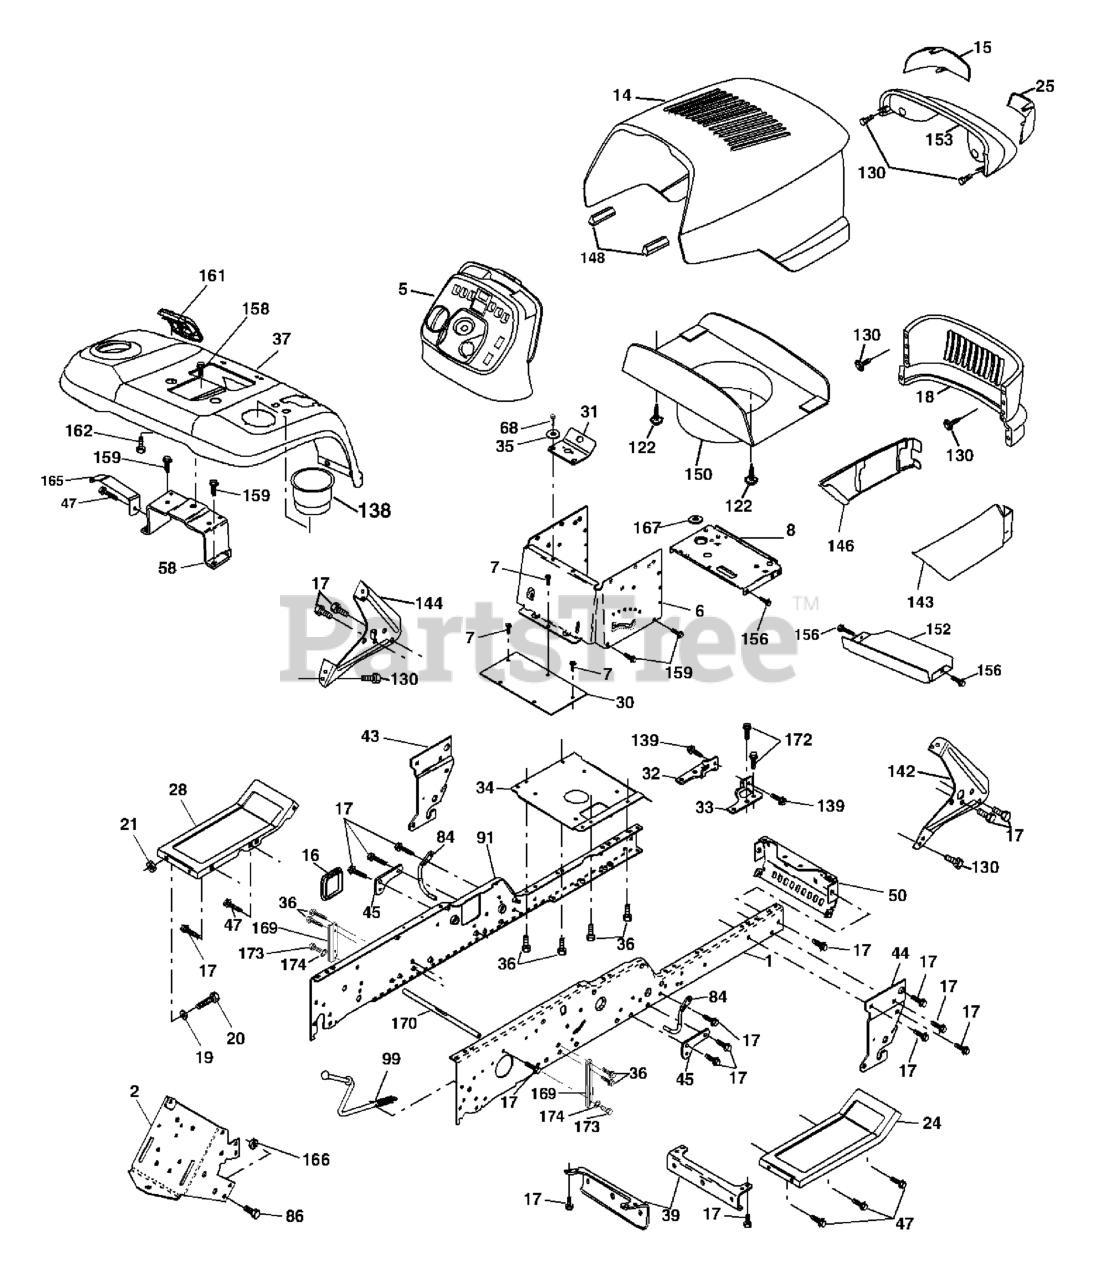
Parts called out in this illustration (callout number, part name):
1	KIT.RAIL.CHASS.RH.GT
2	DRAWBAR, GT
5	DASH
6	DASH VGT, LOWER
7	SCREW
8	SUPPORT, BATTERY
14	HOOD
15	LENS LH
16	COVER ACCESS
17	SCREW, 3/8-16X3/4
18	GRILLE.STEALTH P/L.YTGT.GREY
19	WASHER
20	BOLT
21	NUT
24	FOOTREST PNT RH
25	LENS RH
28	FOOTREST PNT LH
30	SADDLE.HYDRO.95
31	BRACKET SUPT 1-PC VGT STEERING
34	PLATE ASM ENG CHASSIS
35	WASHER
36	SCREW 5/16"
37	KIT.FENDER.YTGT.W/S
39	BRACKET AXLE, FRONT
43	FRONT SUSPENSION BRKT LH
44	FRONT SUSPENSION BRKT RH
45	BRACKET ARM SUSPENSION
47	SCREW LT
50	BRACKET, CHASSIS FRONT
56	BRACKET ASM., SUSP CHASSIS LH
58	BRACKET ASM., FENDER
68	Screw, 5/16-18 x 1/2
84	UPSTOP 54"
86	BOLT FIN HEX 7/16-14 X 1
91	KIT.RAIL.CHASS.LH.GT
99	ROD ASM, BYPASS
122	SCREW.WSHD.HEX10-32X5/8
130	SCREW
138	CUPHOLDER.YTGT.TWIST L
139	BOLT, SHOULDER 5/16-18
142	BRACKET DASH STEALTH(R)
143	SKIRT GRILLE RH
144	BRACKET DASH STEALTH LH
146	SKIRT GRILLE LH
148	EXTRUSION BUMPER (3 2) (2 2)
150	DUCT.HEAT.HOOD.STEALTH.GT
152	BROWNING SHIELD
153	LIGHTBOX.ASM.STV.DL.INC.HUSQ
156	SCREW
158	SCREW 3/8-16X1/2
159	SCREW, 3/8-16X3/4
161	CONSOL.FUEL.WINDOW.BLACK
162	SCREW.HI-LO.CONSOLE
165	BRACKET SUPPORT TANK
166	Nut, Lock Hex 7/16-14 unc
167	BUSHING SNAP
169	BRACKET CHASSIS SWAY
170	ROD.BRKT.SWAY
172	SCREW 3/8-16X.875
173	BOLT.FIN.HEX.5/16-18X3/4
174	WASHER.LOCK.HVY.HLCL.SPR.5/16
